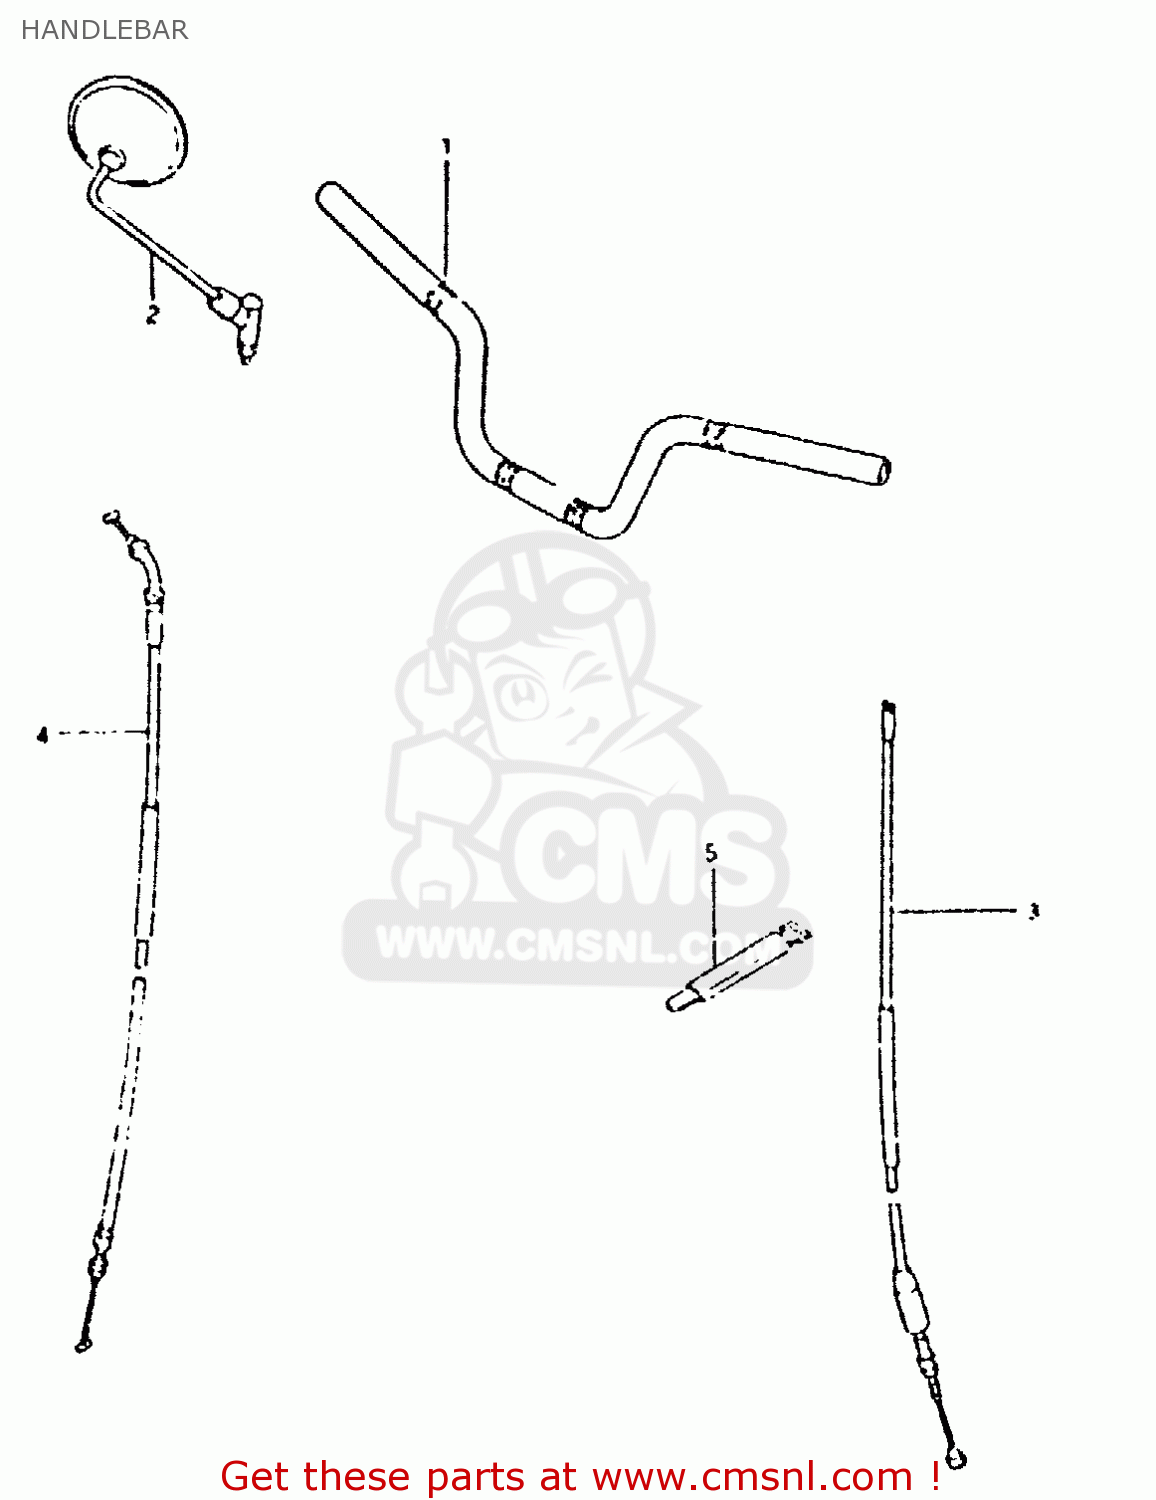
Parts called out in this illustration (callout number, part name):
1	HANDLEBAR
2	MIRROR ASSY,RH
3	CABLE ASSEMBLY,CLUTCH
4	CABLE ASSEMBLY,THROTTLE
5	CLAMP
